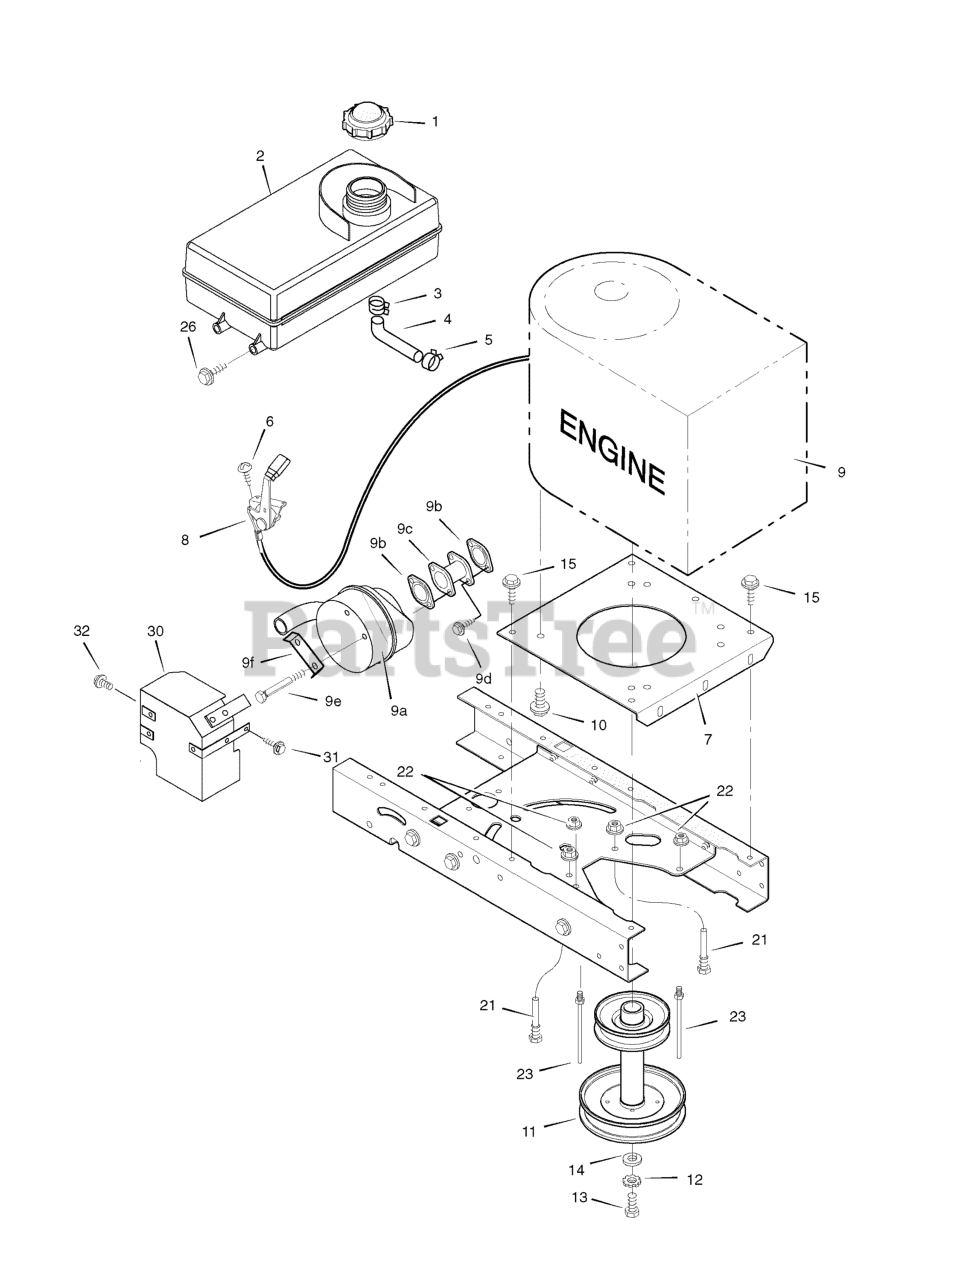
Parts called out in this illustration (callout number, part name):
1	Fuel Cap
2	TANK, Fuel 1.4 Gal.
3	Hose Clamp
4	Fuel Line (Must cut to length)
5	Hose Clamp
7	Plate, Engine
8	Throttle Control
9	Engine, Briggs & Stratton *
10	Bolt, Engine Mount
11	STACK PULLEY ASSEMBLY
12	Lockwasher
13	Bolt, Hex
21	Guide, Belt
22	Nut, Flange
23	Guide, Belt
30	Shield, Heat
